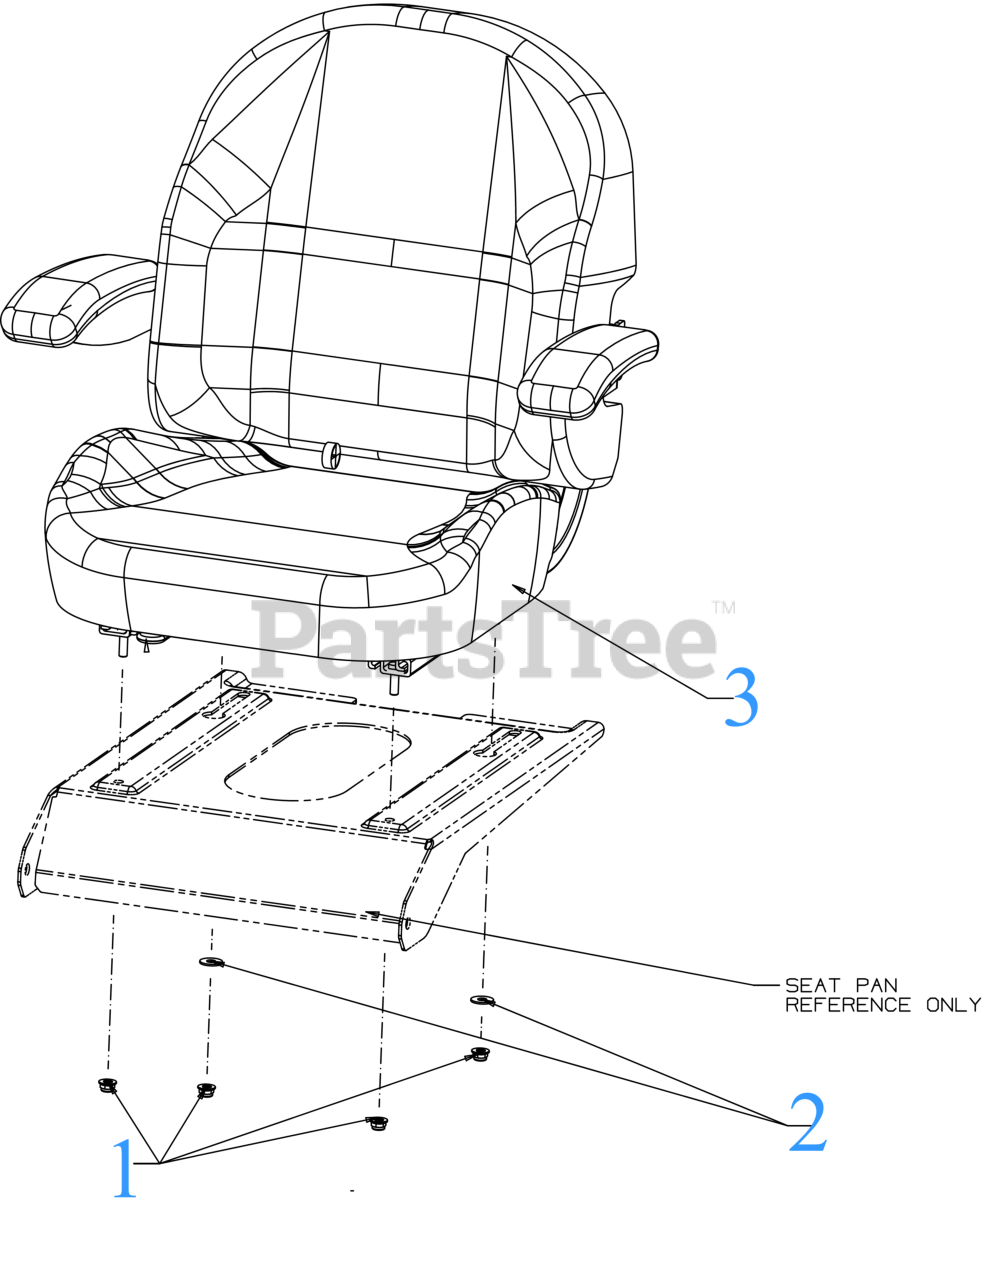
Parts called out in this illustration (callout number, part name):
1	FLANGE LOCK NUT 5/16-18
2	FLAT WASHER
3	SEAT (SLIDE/ARMREST)
3	SET OF NON ADJUST ARMREST KIT
3	SEAT BACK REPLACEMENT COVER
3	SEAT CUSHION REPLACEMENT COVER
3	DOME COVER SEAT SWITCH
3	SEAT SWITCH NC/NO
3	SEAT SWITCH (NC/NO)
